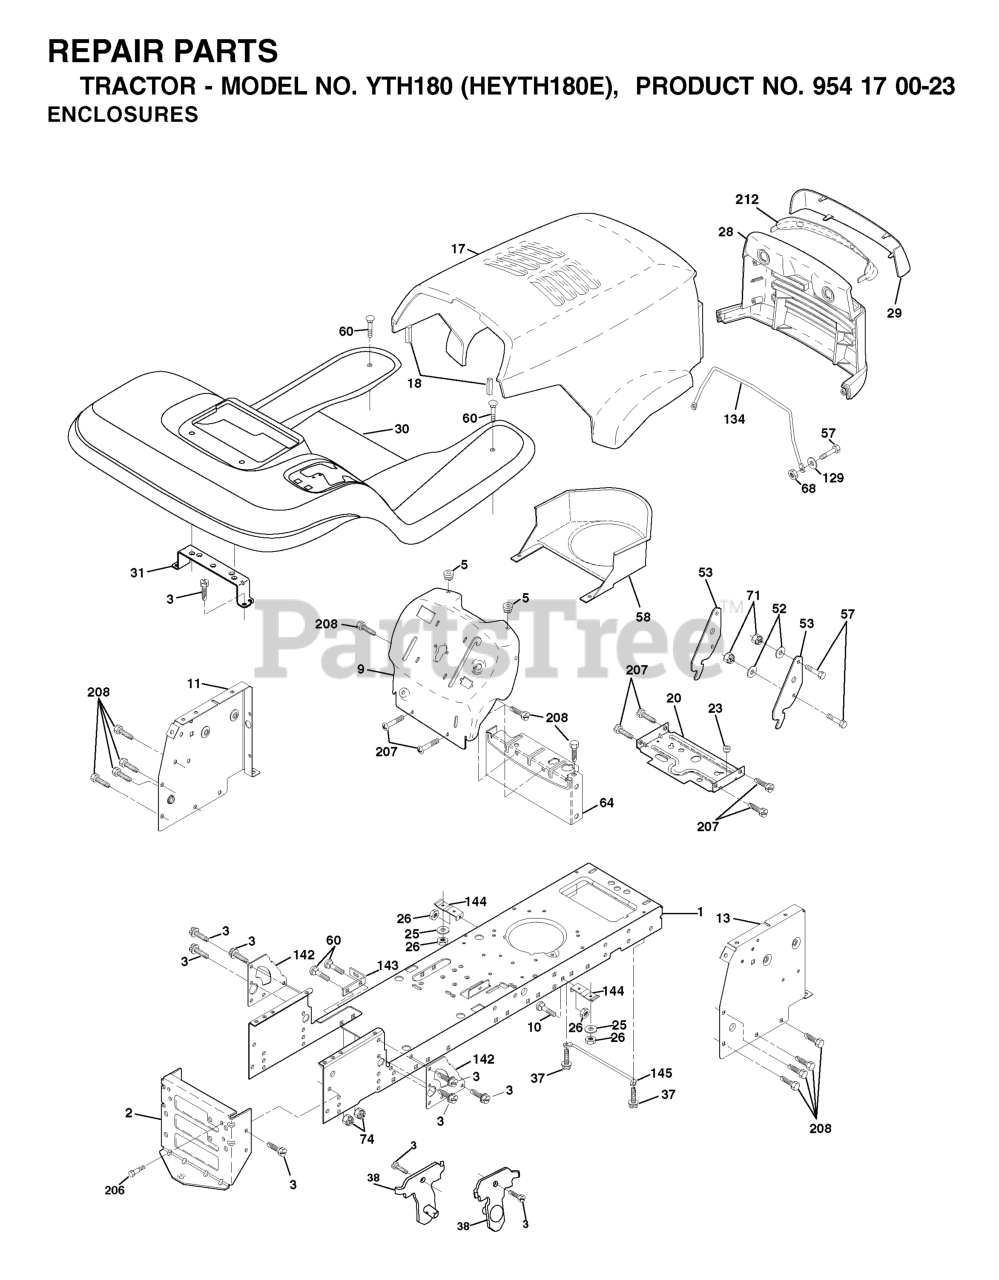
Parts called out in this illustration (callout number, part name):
2	DRAWBAR
3	SCREW 3/8-16X3/4
5	BUMPER.RUBBER.HOOD
9	DASH(SUBS)
10	BOLT D
11	PANEL DASH LH
13	PANEL ASM, DASH RH
17	HOOD
18	BUMPER HOOD T
20	PLATE MTG
23	BUSHING.SNAP.NYL.BLK.
25	WASHER
26	NUT
28	GRILL
29	LENS
30	FENDER FOOTREST
31	BRACKET.SUPPORT.FENDER
37	Screw 5/16-18 x 1/2 Hex, Self Tapping 5/16-18 x 1/2
38	BRACKET
53	BRACKET PNT PICK OFF LT/PL
57	BOLT
58	DUCT, INTAKE AIR
60	Bolt - Rd. Hd. Sq. Neckiage 3/8 16 x 3/4
64	DASH LOWER
68	NUT
71	NUT.CROWNLOCK.1/4
134	ROD SUPPORT HOOD LT/PL HUS.
142	PLATE
143	BRACKET, SWAY BAR
144	BRACKET FOOTREST
145	ROD PIVOT CHASSIS/HOOD
206	SHOULDER BOLT 5/16-18TT
207	SCREW, 5/16-18 X 1/2
208	SCREW 3/8-16X1/2
212	INSERT LENS REFLECTOR
